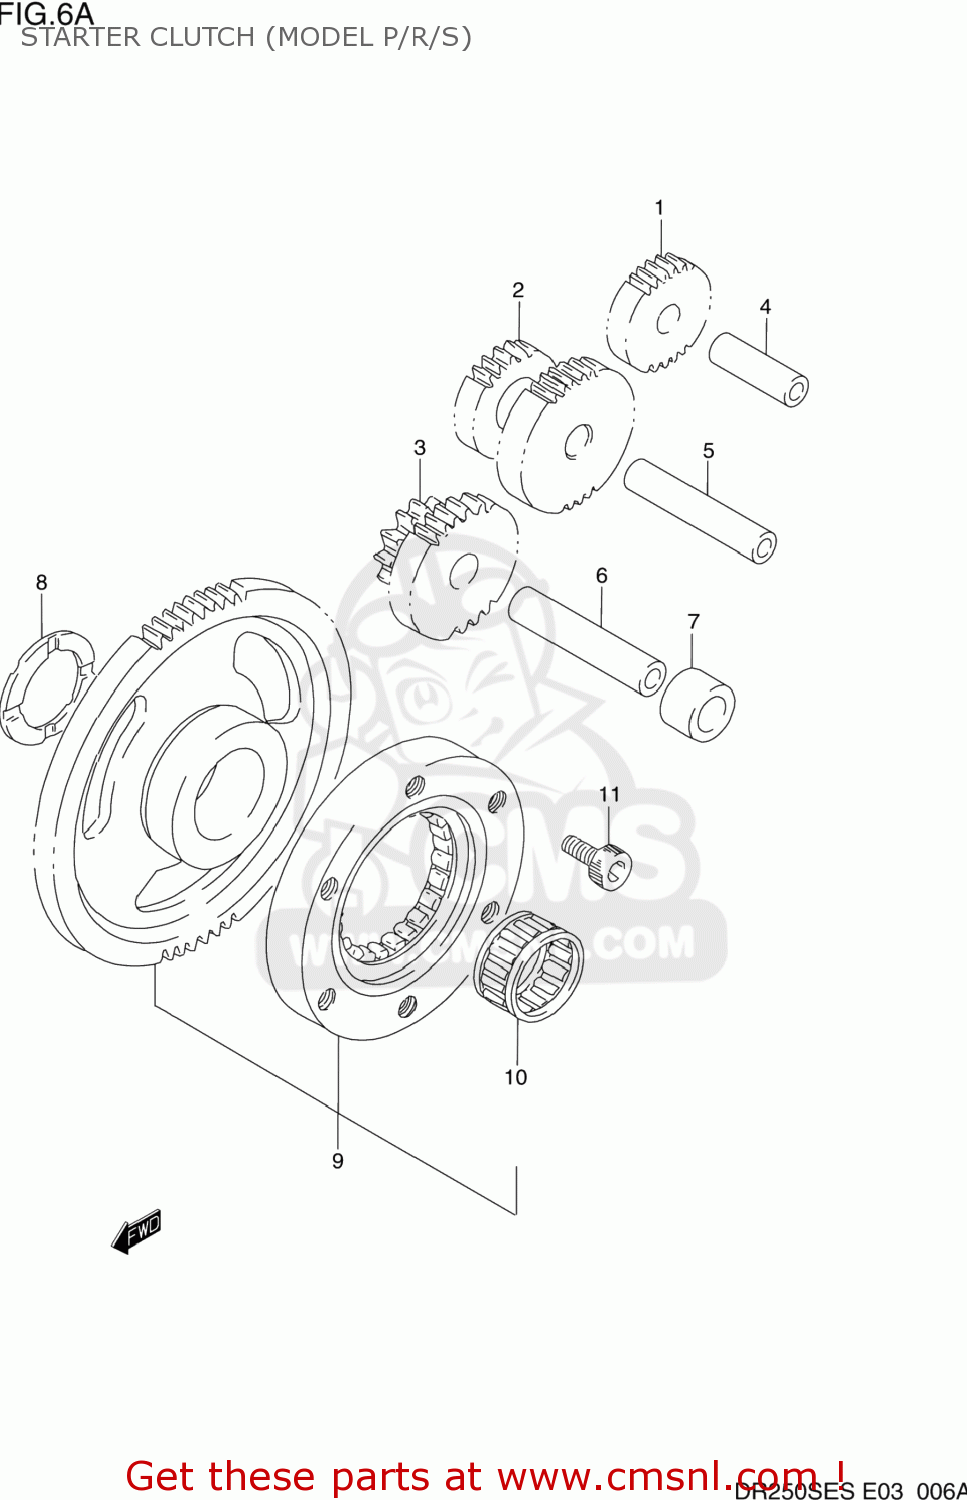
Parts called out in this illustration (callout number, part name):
1	GEAR,STARTER IDLE NO.1(NT:34)
2	GEAR,STRTR IDLE NO.2(NT:22/47)
3	GEAR,STARTER IDLE NO.3
4	PIN(6X10X32)
5	PIN(6X10X55.5)
6	PIN(12X55.5)
7	SPACER (12.2X20X13)
8	WASHER(27X40X2.5)
9	CLUTCH SET,STARTER
10	BEARING 27X32X18
11	BOLT
